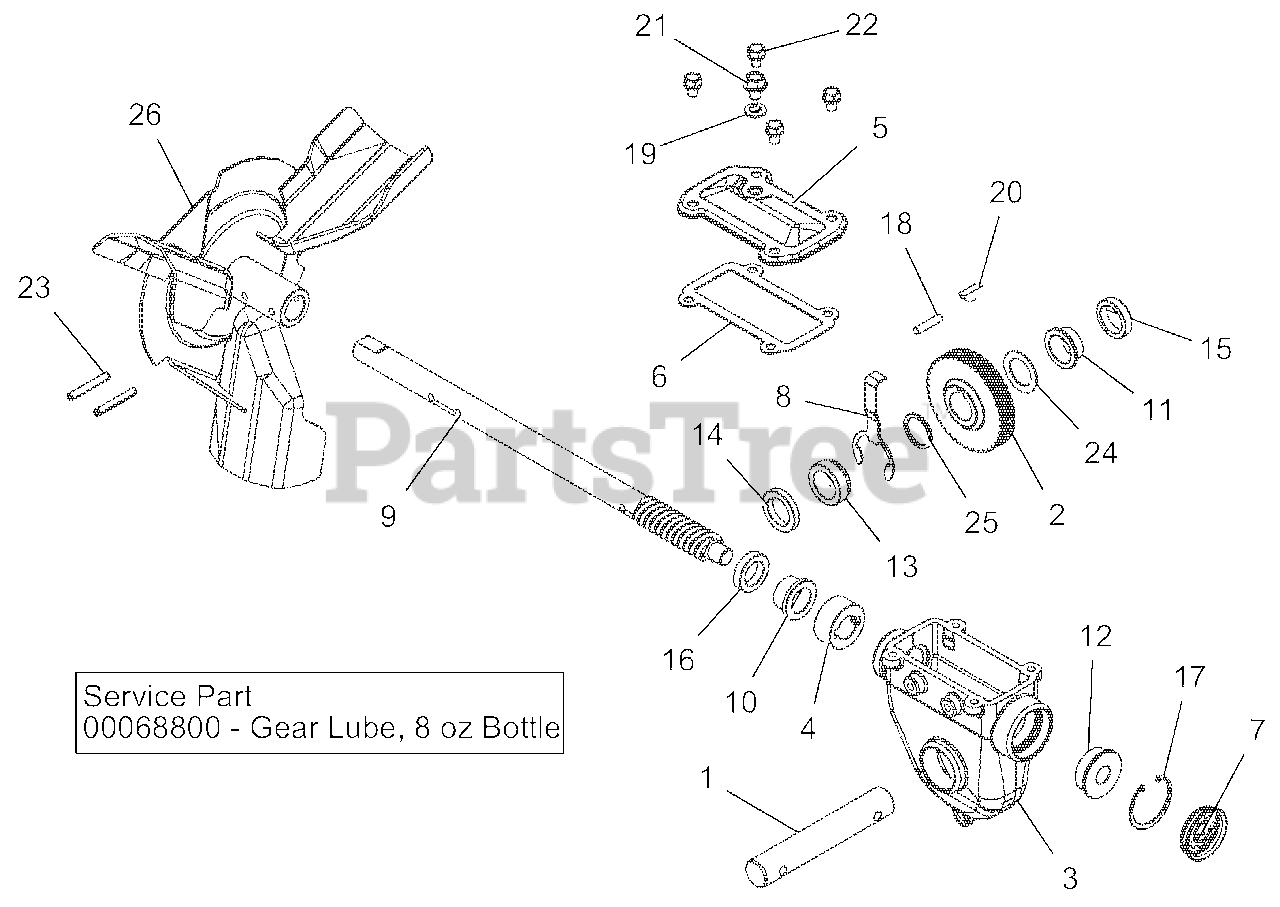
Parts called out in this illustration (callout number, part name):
1	RAKE SHAFT, SHORT-COMMON
2	WORM SHAFT & GEAR
3	GEARCASE, LARGE MACHINED
4	THRUST COLLAR, .875"ID SLIPFIT
5	COVER, TOP - LARGE IRON
6	GASKET, TOP - LARGE GEARCASE
7	COVER, GEAR CASE 1.75"
8	BUSHING RETAINER, LARGE
9	WORM SHAFT & GEAR
10	BSHG-FLG .879X1.128X.75X1.45
11	BSHG-FLG 1.006X1.128X.555X1.45
12	BSHG-FLG .628X1.503X.58X1.725
13	BSHG-FLG LARGE, RIGHT
14	SEAL-OIL .999X1.500X.250 TBC29
15	SEAL-OIL .999X1.375X.312 TBC29
16	SEAL-OIL .873X1.375X.312 TBC29
17	RG-RTNG-INT 1.750X.062
18	PIN-STR .250X1.12 6150
19	WSHR-BND-SEAL .38X.75X.11 GALV
20	KEY-WDRF .25X.875 HRD #A
21	@SCR-ROLOK .38-16X.50 HWH YWZC
22	BOLT, SEMS .31-18X.50 GR5 YWZC
23	PIN-ROLL .250X1.75
24	WSHR-FL-STL 1.010X1.505X.062YZ
25	WSHR-FL-STL 1.010X1.250X.068YZ
26	IMPELLER, 3 BLADE-14"
